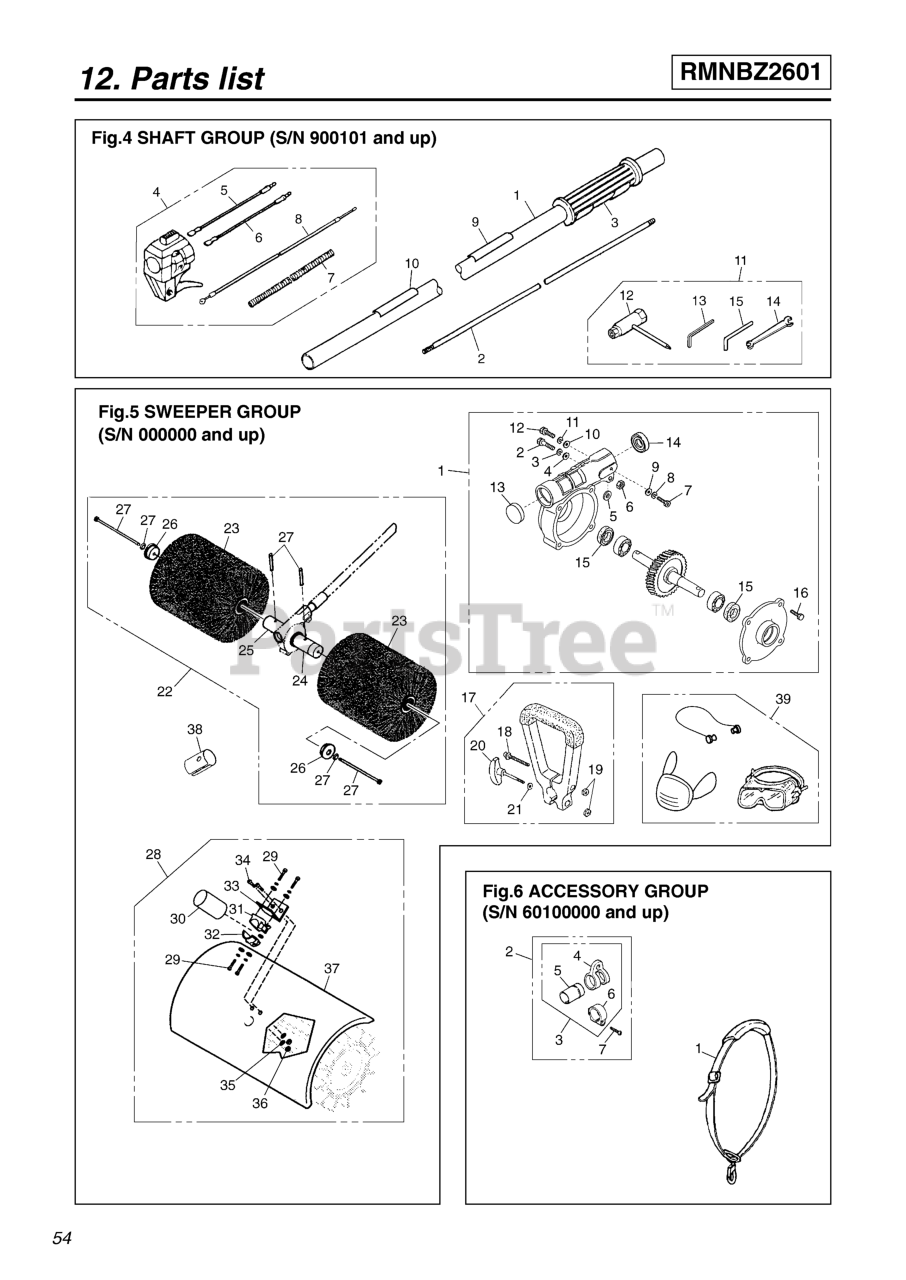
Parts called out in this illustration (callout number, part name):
1	PIPE COMPLETE
3	GRIP (RPLS 3577-32140 & 3220-
5	CORD (A), BLACK
6	CORD (B), RED
7	TUBE (RPLS 4900-72141)
8	CABLE (RPLS 5580-83100)
9	NAMEPLATE
10	PLATE, CAUTION
12	SOCKET
13	WRENCH (TOOL)
14	SPANNER, 8 X 10 (RPLS 2540- )
15	BAR
A2	BOLT, M6 x 30
A3	SPRING WASHER
A4	WASHER, FLAT
A5	WASHER, FLAT
A6	NUT, M6 X 5
A7	BOLT, M5 x 12
A8	WASHER, SPRING M4 x 1.3
A11	WASHER, SPRING M4 x 1.3
A12	SCREW
A13	PLUG, HOUSING
A16	SCREW
A17	HANDLE ASSY (RPLS 99909-33009)
A22	BRUSH SWEEPING ATTACH (NYLON)
A23	BRUSH, NYLON
A24	ADAPTOR, GEAR SHAFT, LH
A25	ADAPTOR, GEAR SHAFT, RH
A27	KIT, BRUSH HARDWARE
A28	DEBRIS SHIELD ASSEMBLY
A31	BRACKET, HANDLE
A32	CAP, LOWER
A33	BRACKET, SHIELD
A39	SAFETY KIT
B2	HANGER ASSEMBLY
B3	HANGER COMPLETE
B4	HANGER
B5	CLAMP
B6	SLEEVE
B7	SCREW, M5 x 25
